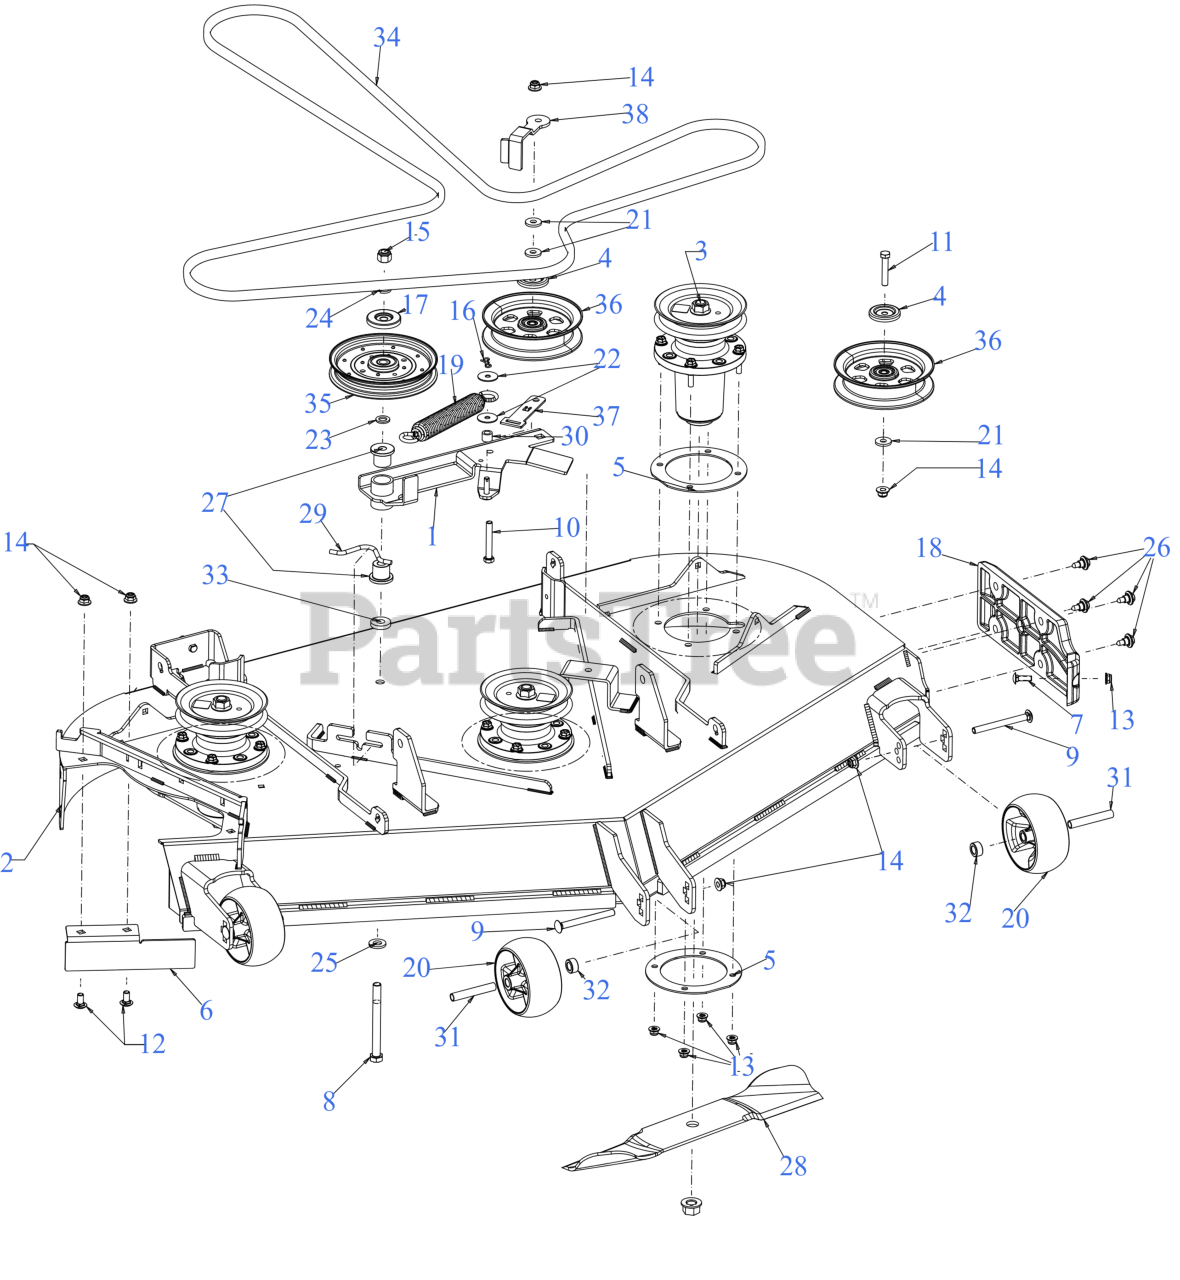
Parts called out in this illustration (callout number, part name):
1	54/60" DECK IDLER ASSEMBLY
2	54" FAB DECK SHELL
3	SPINDLE ASSEMBLY
4	PULLEY CAP 1.875 DIA
5	SPINDLE PLATE
6	54" DECK CHUTE BAFFLE
7	CARRIAGE BOLT 5/16-18 x 1.00
8	BOLT-HEX 1/2-13X5.0 GR5
9	CARRIAGE BOLT 3/8-16 x 4.00 GR5
10	HEX SCREW-3/8-16X2.5 GR5
11	SCREW 3/8-16 x 2.0 GR5
12	CARRIAGE BOLT 3/8-16 x .75
13	FLANGE LOCK NUT 5/16-18
15	HEX LOCK NUT NYLON
16	BOW TIE COTTER PIN 1/4-5/16
17	PULLEY CAP 1/2"
18	DECK SKID PLATE
19	SPRING 1.25" DIA x 8.5" LONG
20	DECK WHEEL
21	FLAT WASHER .385 x 1.00 x .135
22	FLAT WASHER .322 ID x 1.25 x .060
23	FLAT WASHER
24	LOCK WASHER 1/2
25	FLAT WASHER .531X1.060X.134
26	SHOULDER SCREW .43X.29X5/16-18 TT
27	FLANGE BEARING
29	DECK SPRING HOOK
31	SPACER .38X.49X3.05LG
32	SPACER-.505 1D
33	SPACER PLATE
34	V-BELT B SEC x 148.25
35	IDLER PULLEY 6.0" DIA
36	5" FLAT IDLER PULLEY
37	BELT KEEPER
38	54/60" IDLER KEEPER
